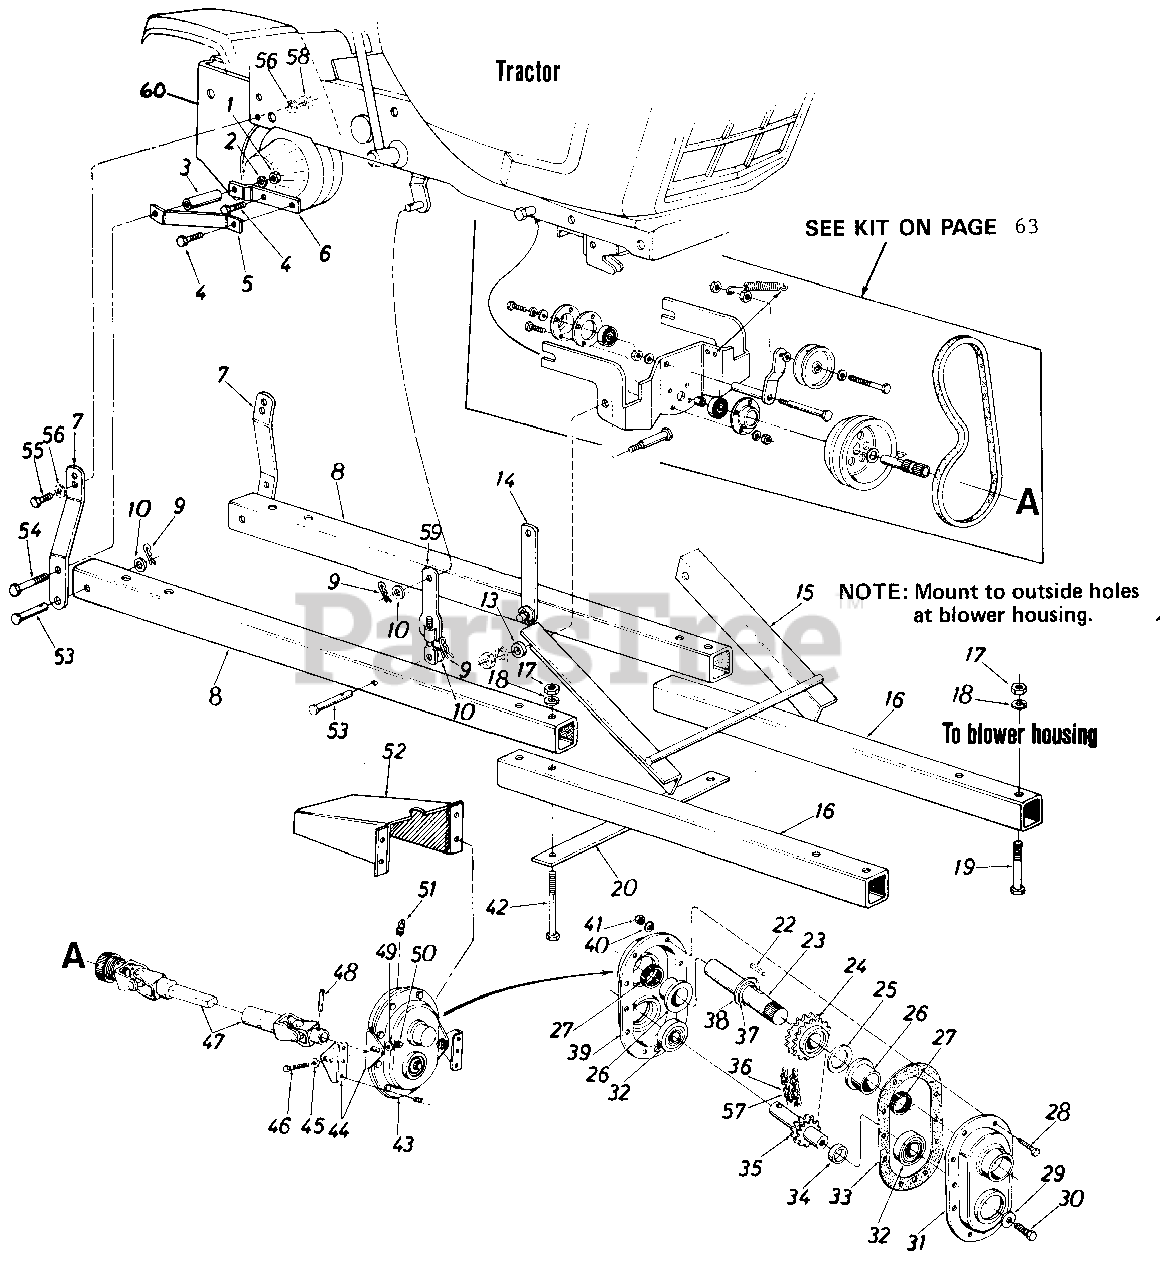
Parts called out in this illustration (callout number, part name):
1	Hex Jam Nut 7/16-20 Thd.
2	L.-Wash. 7/16" I.D.*
3	Spacer .50" I.D. x 1.0" O.D. x 1.47" Lg.
4	Patch Bolt 3/8-16 x 2.5" Lg. (Grade 5)
8	Sq Tubing 2" x 46" Lg.
9	Internal Cotter Pin 1/2" Dia.
10	Fl.-Wash. .510" I.D. x 1.0" 0.D.
13	Shld. Spacer .625" I.D.
14	Lift Bracket 1-1/4" x 7.0" Lg.
15	Guide Bracket Ass'y.
16	Sq. Tubing 2.0 x 35.25" Lg.
17	Hex Nut 1/2-13 Thd.*
18	L.-Wash. 1/2" I.D.*
19	Hex Bolt 1/2-13x3.00" Lg.*
20	Tubing Support Bracket
22	Sq. Key 1/4 x 1.00" Lg.
23	Gear Shaft
24	Double Sprocket 19-2 Teeth x.50" Pitch
25	Fl.-Wash. 1.25" I.D. x 2.00" O.D.
26	Flange Bearing 1.252" I.D.
27	Oil Seal 1.25 I.D. x 1.75" O.D.
28	Hex Bolt 1/4-28 x .88" Lg.
29	Bell.-Wash. .400" I.D. x 1.25' 0.D.
30	Hex L.-Bolt 3/8-24 x 1.00" Lg.*
31	Gear Housing Half - L.A.
32	Ball Bearing 1.00" I.D. x 2.00" O.D.
35	11-2 x .500 Pitch - Sprocket Shaft Ass'y.
36	40-2 Chain 1/2 Pitch x 25 Links
37	Snap Ring for 1.25" Dia. Shaft
38	Fl.-Wash. 1.25" x 2.00" O.D.
39	Gear Housing Half - R.H.
40	L.-Wash. .270" I.D. x .57" O.D.
41	Hex Nut 1/4-28 Thd.
42	Hex Bolt 1/2-13 x 5.00" Lg.*
43	Chain Gear Box Ass'y. Comp.
44	Gear Box Support Bracket
45	Bell.-Wash. .345" I.D. x .88" O.D.
46	Hex Bolt 5/16-18 x .75" Lg.*
47	Universal Drive Shaft Ass'y.
48	Spring Pin Spir. 5/8" Dia. x 2.50" Lg.
49	Bell.-Wash. .345" I.D. x .88" O.D.
50	Hex Nut 5/16-18 Thd.*
51	Grease Fitting
52	Drive Shaft Cover
53	Clevis Pin.50" Dia.x 2.75" Lg.
54	Hex Bolt 7/16-20 x 3.0" Lg.
55	Hex Bolt 3/8-16 x 1.0" Lg. (Grade 5)
56	L.-Wash. 3/8 " I.D.*
57	Master Link #40 Type IV
58	Hex Nut 3/8-16 Thd.*
59	Adjustable Lift Link Ass'y.-364
60	3-Pt. Hitch Plate Sub Ass'y.
